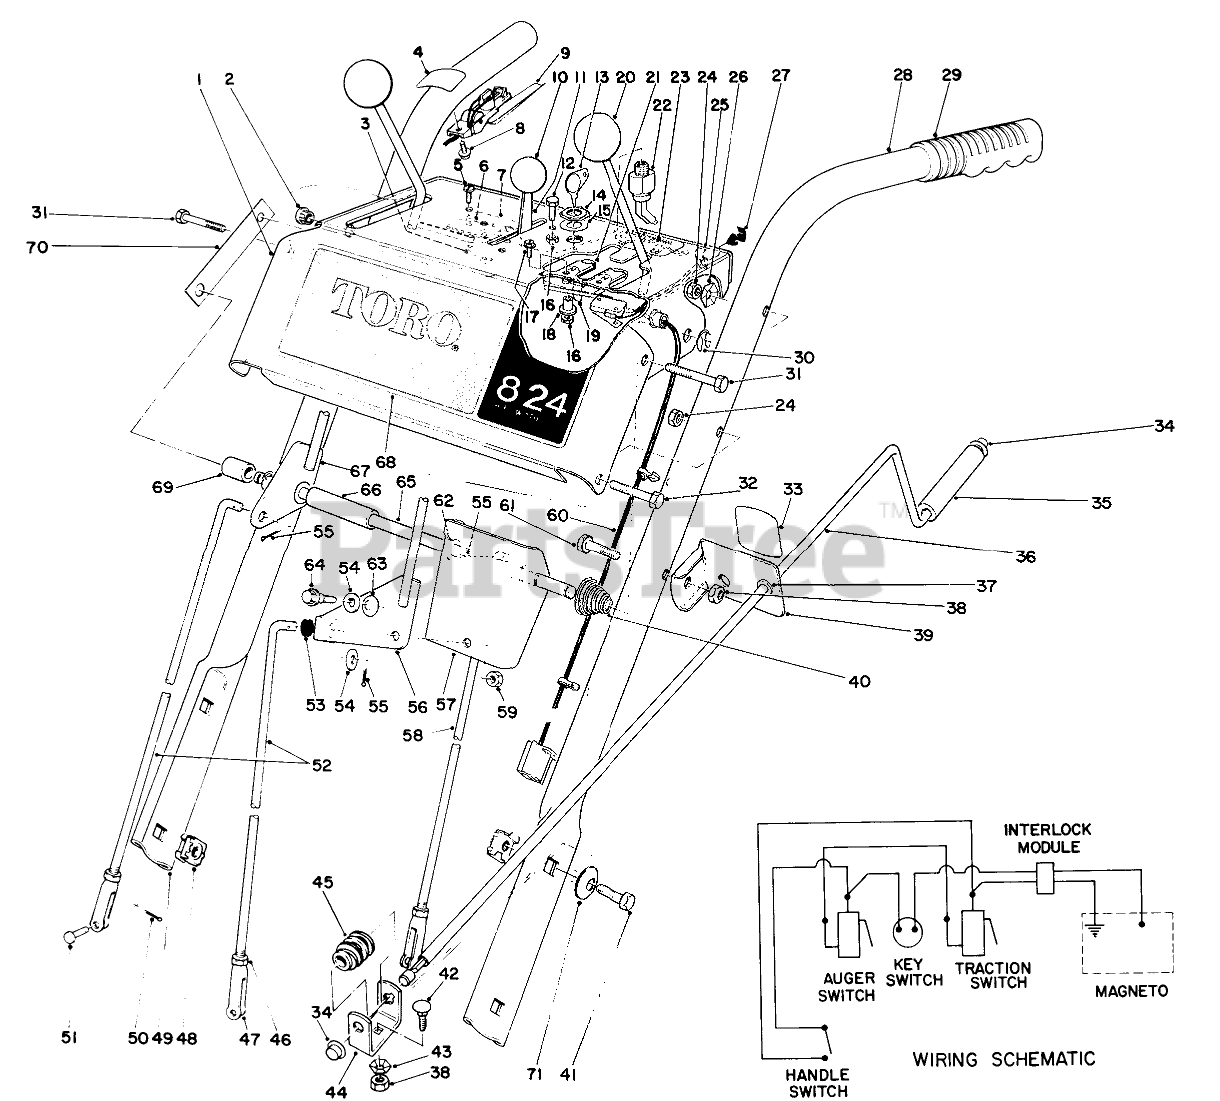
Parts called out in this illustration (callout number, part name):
1	ESCUTCHEON PLT B
2	BUSHING NYLON
3	NUT-SPEED
4	INTERLOCK DECAL
5	SCREW-SPH
6	SWITCH-MICRO
7	SWITCH MTG PAD
8	SCREW
9	INTERLOCK HDLE SWITCH
10	CONTROL KNOB
11	THROTTLE CONTROL
12	HEX HEAD SEMS 10-24X1/2
13	KEY-IGNITION
14	NUT-HH
15	WASHER-TOOTH, INTERNAL
16	NUT-LOCK, NI
17	10-24 X 7/8 RND HD MS
18	INTERLOCK SPACER
19	INTERLOCK SPRING
21	Slide Interlock
22	On-Off Switch (Incl Ref. #14 & 15)
23	INSTR DECAL
24	NUT-LOCK, CONE
25	WIRE CLAMP
26	Washer
27	Mounting Stud
28	LEFT HANDLE
29	Grip Handle
30	RING-CLIP
31	SCREW-HH
32	SCREW-HH
33	DECAL-CHUTE DIRECTION
34	RETAINER-PUSH ON
35	GRIP-CONTROL, CHUTE
36	CHUTE CONTROL ROD
37	Bushing
38	NUT-LOCK, NI
39	Chute Control Rod Mounting (Incl. Ref. #33 & 37)
40	CONICAL SPRING
41	SCREW-HH
42	BOLT-CARR
43	WASHER-LOCK
44	BRACKET-WORM
45	GEAR-WORM, CHUTE
46	NUT-HJ
47	CLEVIS
48	Retained Nut
49	HANDLE RIGHT
50	PIN-COTTER
51	PIN-CLEVIS
52	SPEED SELECTOR ROD
53	GROMMET-RUBBER
54	WASHER-FLAT
55	PIN-COTTER
56	SHIFT LEVER WA
57	SHIFT BRACKET
58	TRACTION CONTROL ROD
59	NUT-LOCK, CONE
60	WIRE HARNESS INTERLOC
61	SCREW-HH
62	WASHER-FLAT
63	7/16 SPRING WASHER
64	SHOULDER SCREW
65	PIVOT ROD
66	SHIFT LEVER SPACER
67	LEVER WA
68	ESCUTCHEON DECAL
69	AUGER LEVER SPACER
70	ESCUTCHEON SUPT STRAP
71	WASHER-SPRING
